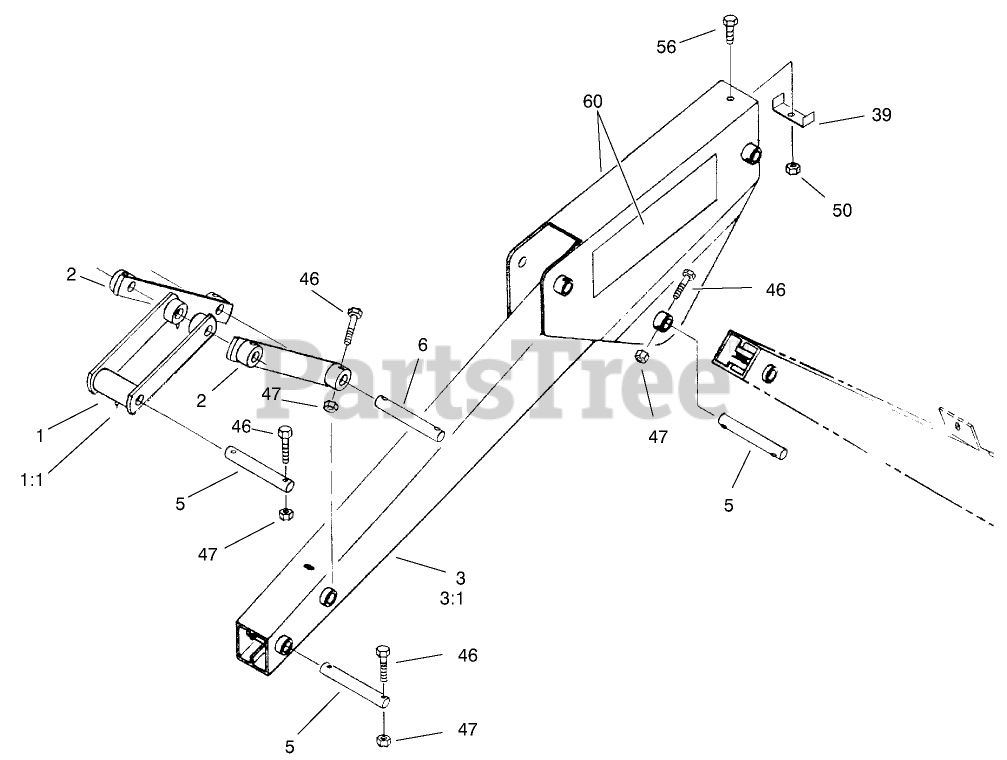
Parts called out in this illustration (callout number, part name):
1	LINKAGE ASM
1:1	FITTING-GREASE
2	LINKAGE STRAP ASM
3	CROWD ARM ASM
5	PIN-BUCKET
6	PIN-LINKAGE
39	BRACKET-HOSE
46	SCREW-HH
47	NUT-LOCK
50	NUT-LOCK, NI
56	SCREW-HH
60	Decal-Front
